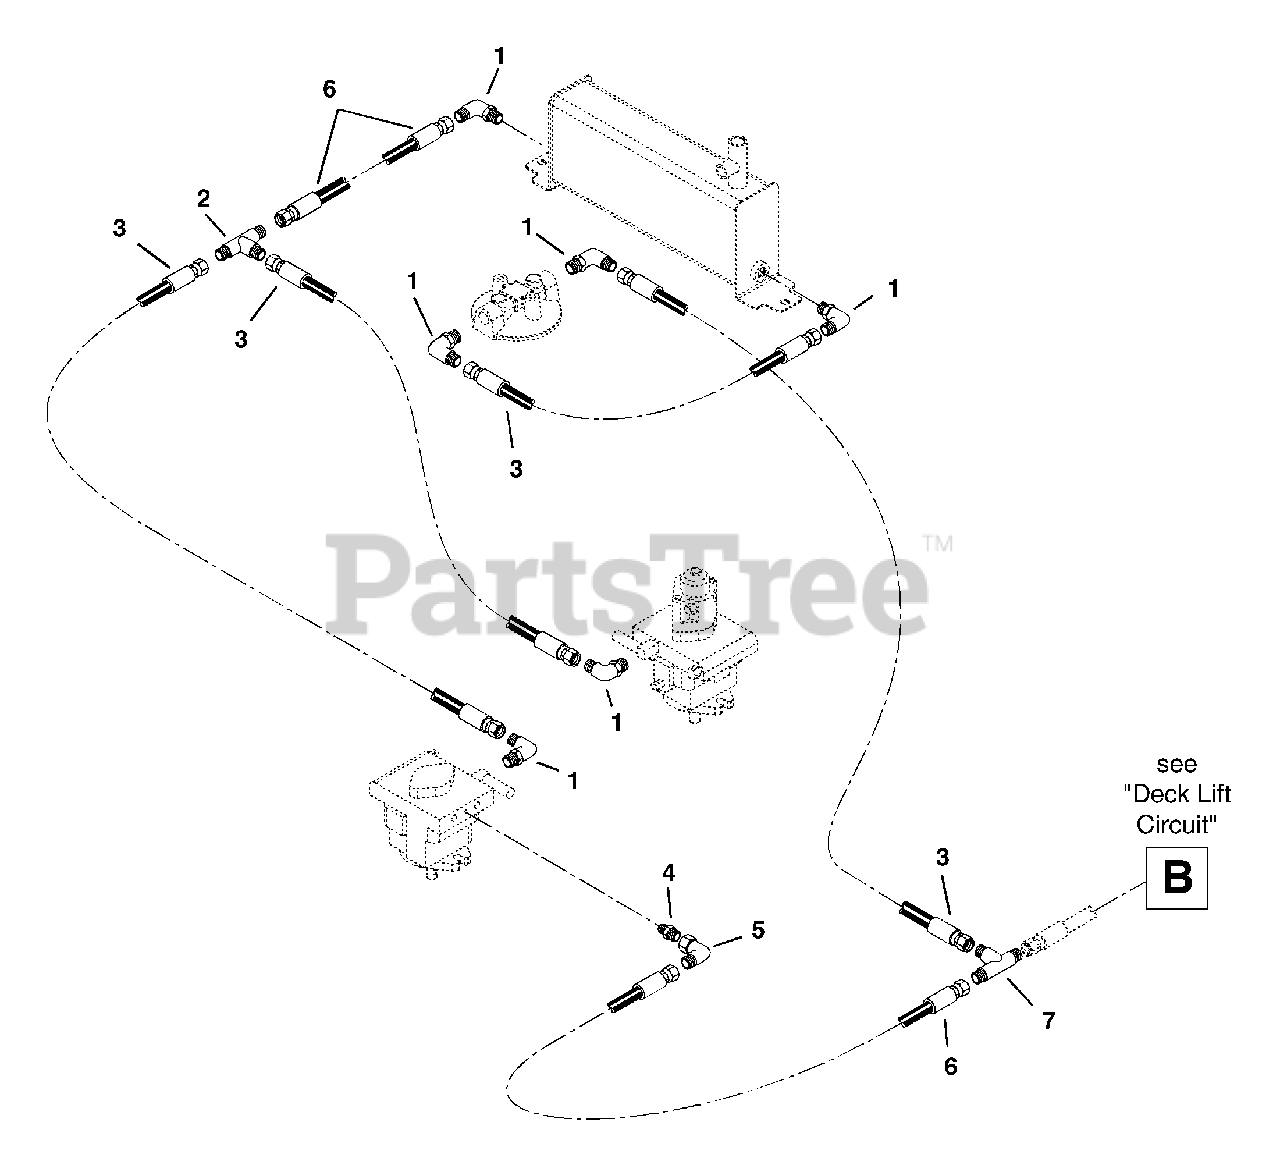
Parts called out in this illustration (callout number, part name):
1	Adapter
2	Adapter-Tee .56 - 18
3	Hose-Hydraulic Valve to Tank
5	Adapter
6	Hose-Pump to Tee
7	Adapter-Tee .56 - 18
